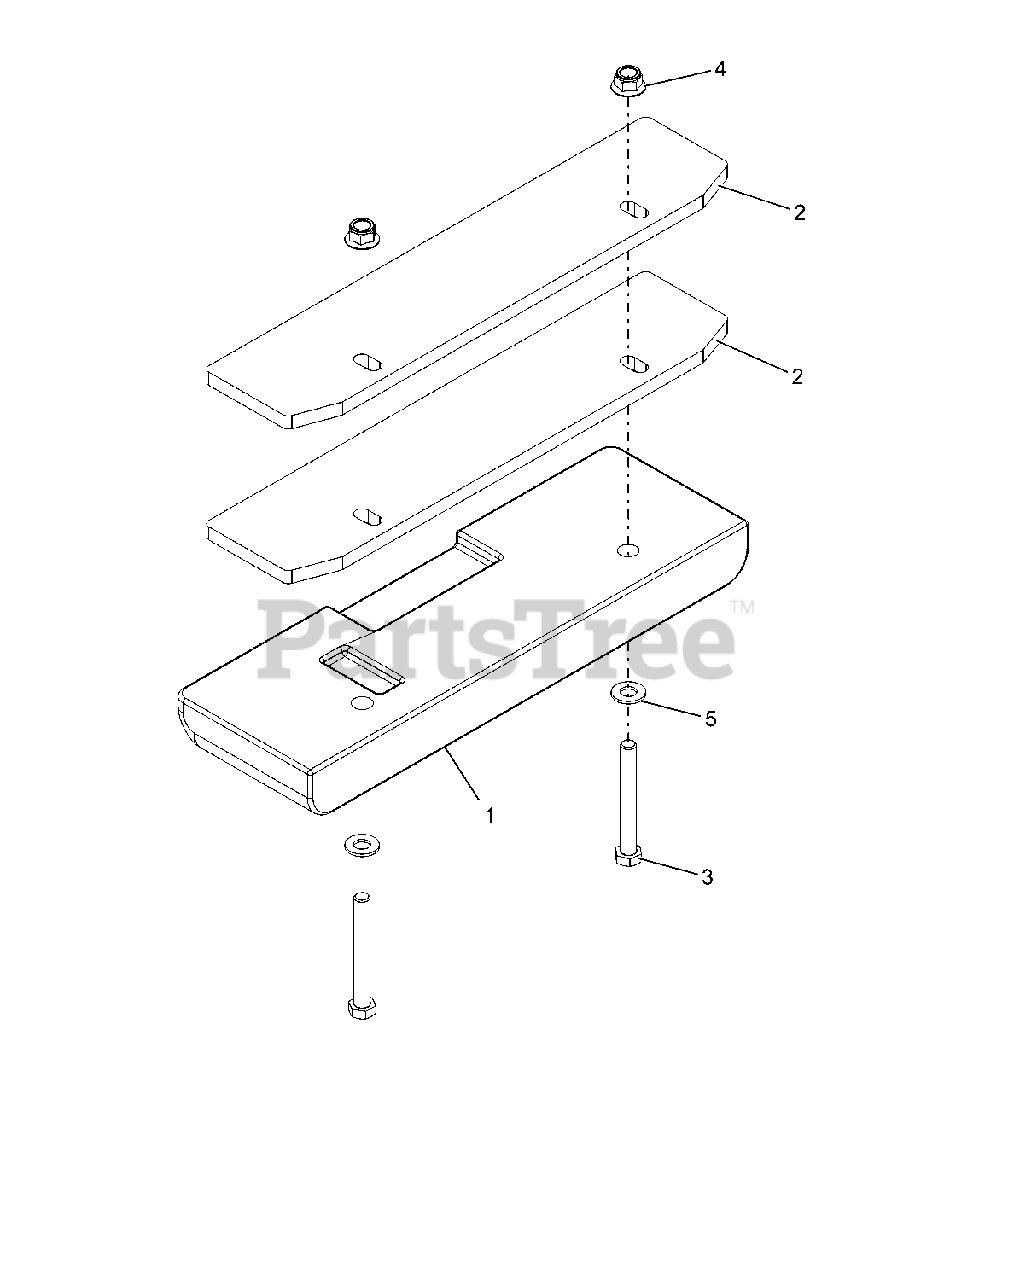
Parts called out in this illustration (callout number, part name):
1	WEIGHT, CAST IRON
2	WEIGHT, COUNTER
3	BLT-HEX .50-13X4.00 GR5 YWZC
4	NUT-LK-NYL-FLG .50-13 YWZC
5	WSHR-FL-STL.531X1.06X.095YWZC
